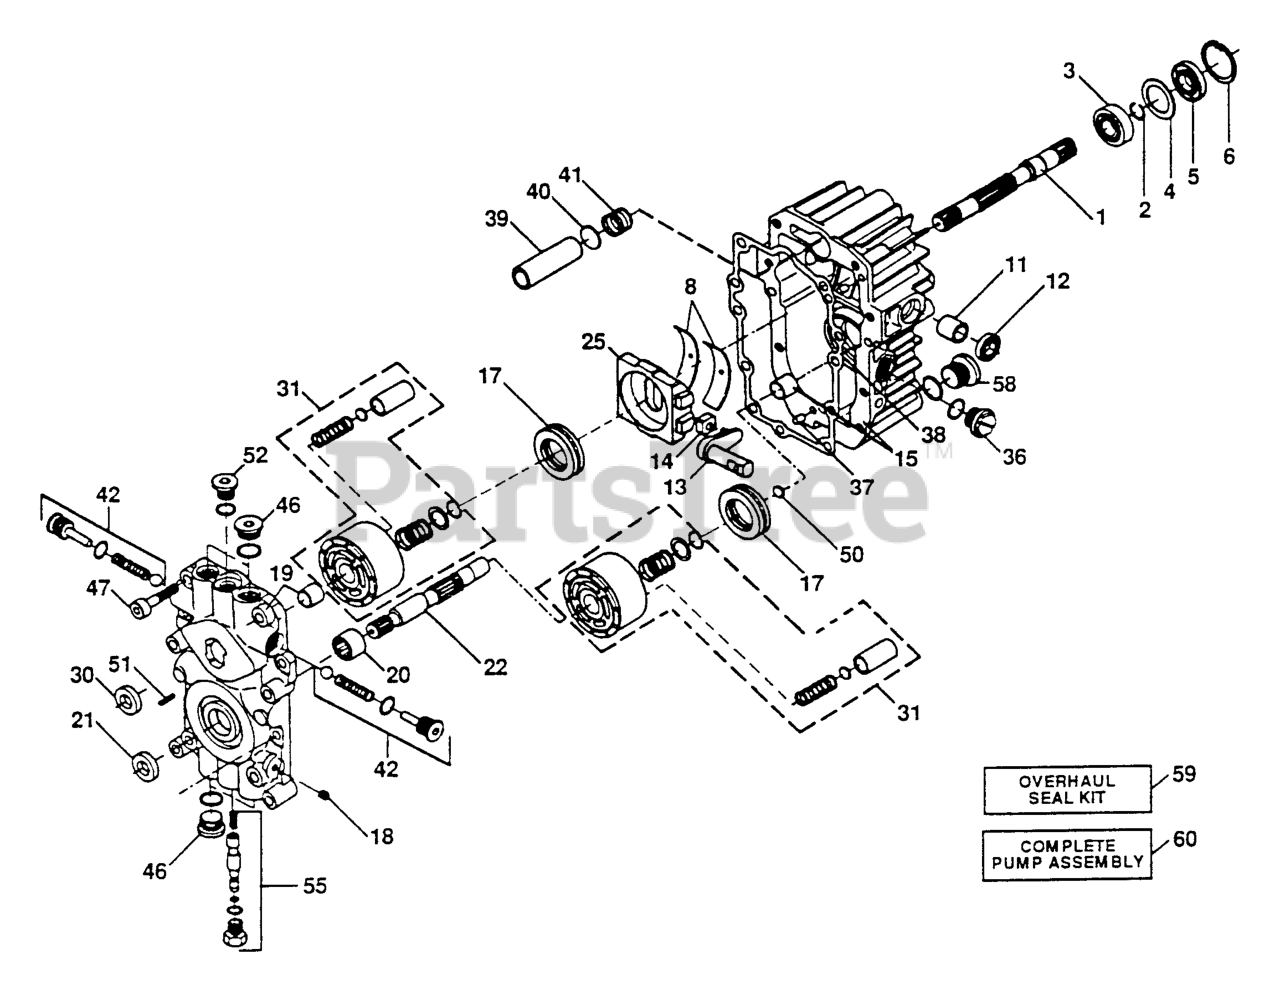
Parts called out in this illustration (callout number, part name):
1	SHAFT 2003022
2	RETAINIANG RING
3	BALL BEARING 2003043
4	SPACER
5	SEAL LIP
6	RETAINING PIN
8	CRADLE BEARING
12	SEAL LIP
13	TRUNION ARM
14	GUIDE 2000015 HYD
15	PUMP ASM COMP
17	BALL BEARING
19	KIT,CTR SECTION
20	NEEDLE BEARING
21	LIP SEAL 9008000-0127
25	SWASHPLATE,VARIAB
30	SEAL LIP
31	KIT,BLOCK CYLINDE
36	PLUG,PLASTIC
38	GASKET 2003060
39	FILTER 2003003
42	KIT,CHECK VALVE 2513014
55	KIT,BYPASS VALVE(2513011)
59	KIT,OVERHEAD SEAL -2513013
60	PUMP ASM COMP
